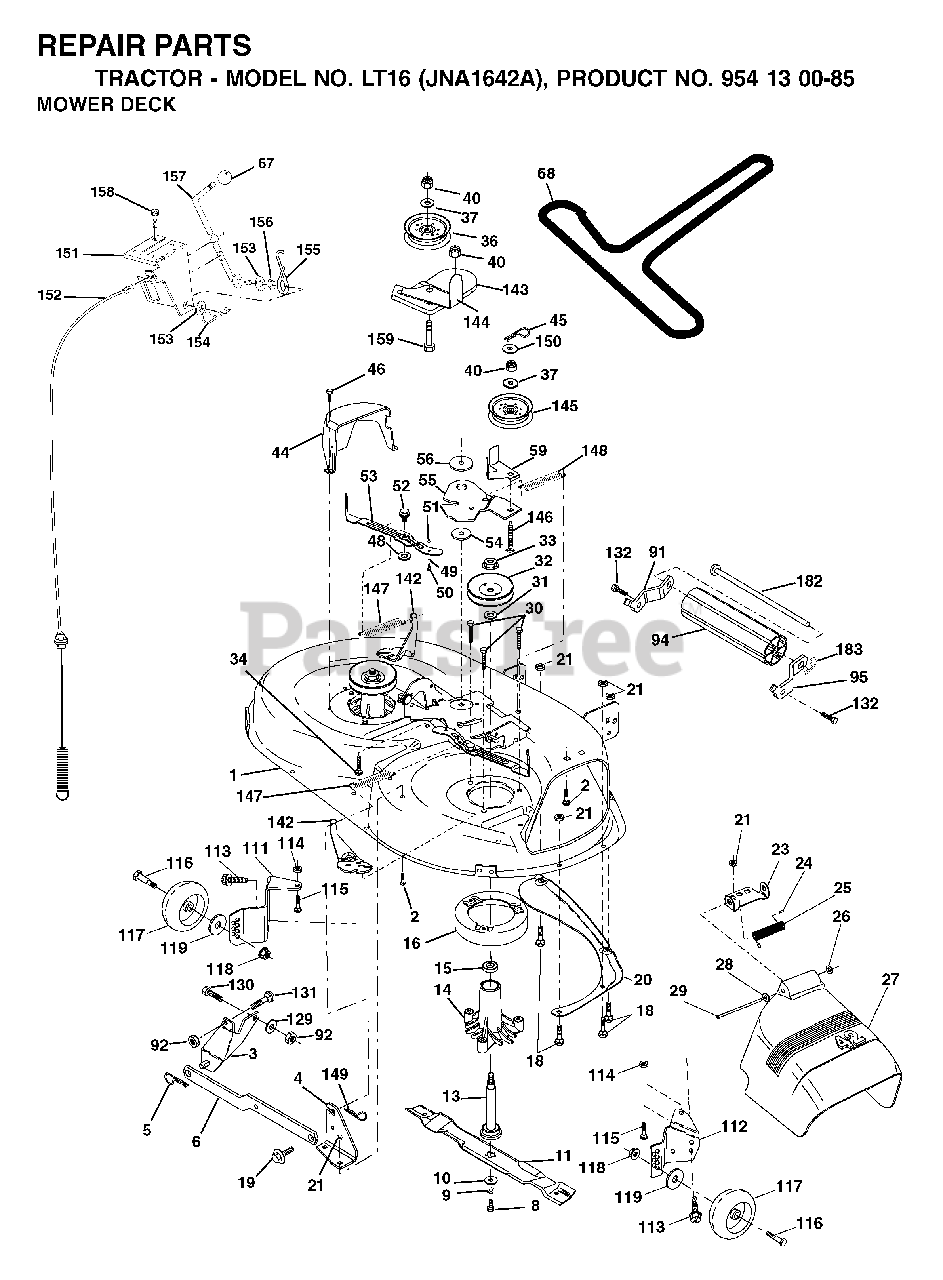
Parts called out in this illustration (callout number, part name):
1	42" DECK KIT
2	BOLT
3	BRKT ASM SWAY BAR
4	BRACKET SWAY BAR 42" DECK
5	RETAINER-SPRNG RB
6	BAR SWAY DECK
8	BLADE BOLT
9	LOCKWASHER
10	WASHER.BLADE
11	BLADE 42"
13	SHAFT ASM VENT
14	HSG MANDREL
16	STRIPPER, MWR ROUND
18	BOLT
19	BOLT SHD 5/16-18
20	BAFFLE.VORTEX
21	LOCKNUT
23	BRKT, DEFL. MOWER
24	CAP-SLEEVE LT
25	SPRING TORSION
26	NUT PUSH M
27	SHIELD DEFLECTOR
28	WASHER
29	ROD.HINGE
30	SCREW, WASHER HEAD
31	WASHER
32	PULLEY/MANDREL
33	NUT, FLG TOPLOCK 9/16"
34	BOLT
36	FLAT IDLER PULLEY
40	LOCKNUT
44	GUARD MANDREL LH BLACK
45	RETAINER M
46	SCREW.1/4-20X5/8
49	ROLLER ASM CAM FOLLOWER
50	BOLT
53	ARM
54	HARDENED WASHER
55	ARM IDLER 42" MOWER LT/YT
56	SPACER.RETAINER.MOWER
59	GUARD, BELT
67	KNOB T (3/8 HOLE)
68	BELT V SECONDARY
91	BRACKET ASM NOSEROLLER LH
92	NUT
94	NOSE ROLLER
95	BRACKET ASM NOSEROLLER RH
111	BRACKET, WHEEL
112	BRACKET, WHEEL
113	SCREW.3/8-16X.625
114	NUT
115	BOLT
117	WHEEL.GAUGE.STANDARD
118	LOCKNUT
119	WASHER
129	WASHER
131	BOLT D
132	SCREW 3/8-16X3/4
142	ARM SPRING BRAKE MOWER
143	BRACKET, ARM IDLER
144	KEEPER.BELT.42".CLUTCH.CABLE
145	PULLEY
146	BOLT, CARRIAGE IDLER BLACK
148	IDLER RETURN SPRING
149	SPRING.RETAINER.YELLOW.ZINC
150	WASHER PM
151	BRACKET, CLUTCH CABLE
152	CLUTCH CABLE 42"
153	WASHER FLAT 3/8"
154	SPRING RETAINER
155	SPRING RETENTION LEVER
156	SPACER CLUTCH CABLE
157	ROD CLUTCH CABLE 3/8"
158	SCREW
159	BOLT
182	ROD ROLLER NOSE STANDARD
183	SPRING RETAINER
